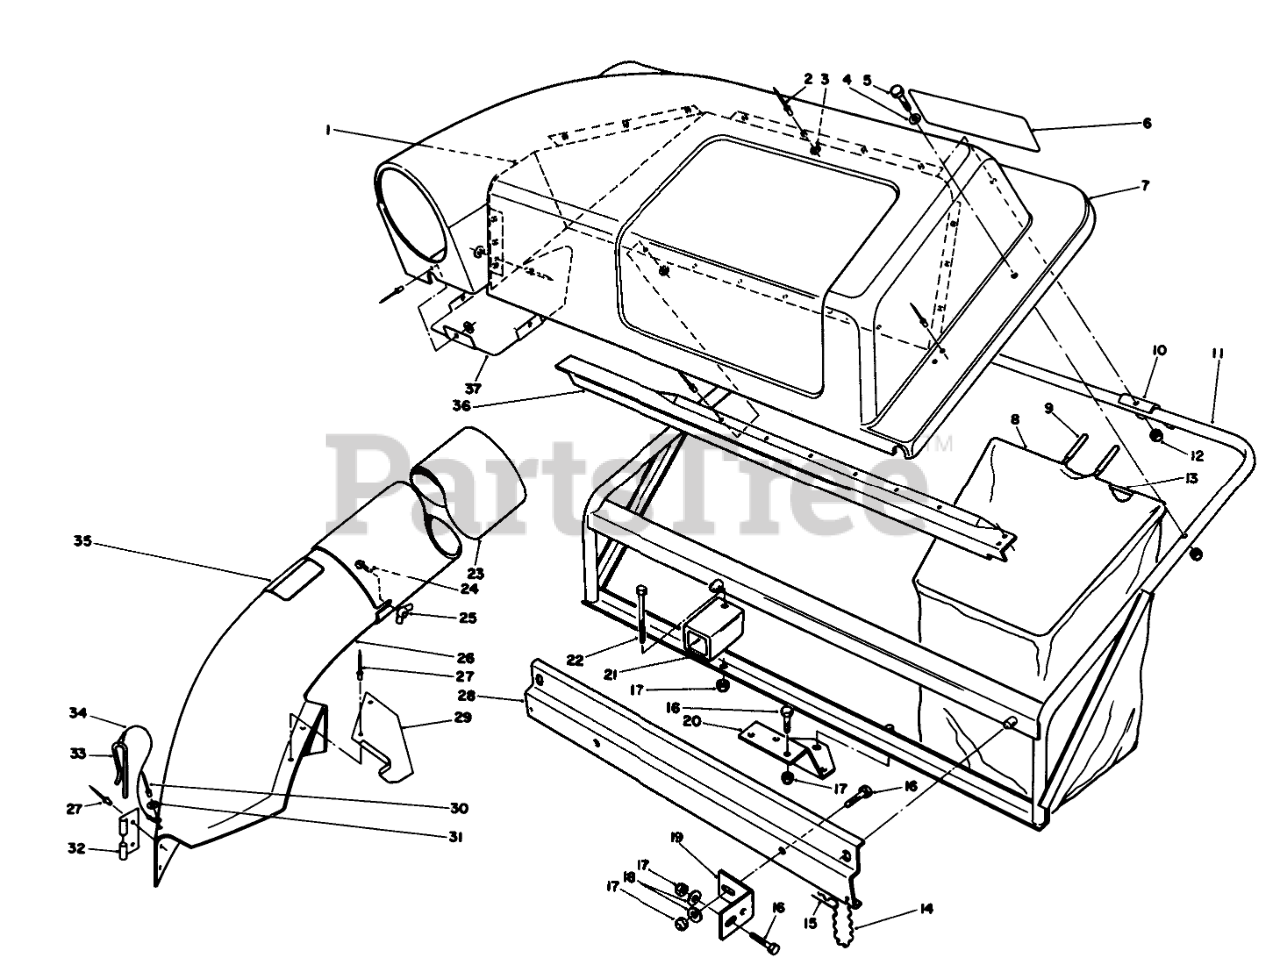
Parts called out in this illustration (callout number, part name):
1	Screen-Cover
2	Rivet-Pop
3	WASHER-FLAT
4	WASHER-PLAIN
5	SCREW-HH
6	TWIN BAGGER DECAL
7	Cover
9	GRIP-HANDLE, BAG
10	BAG FRAME BRKT
11	Frame
12	NUT-LOCK, CAP
13	Frame-Bag
14	Chain
15	PIN-HAIR
16	Screw
17	NUT-LOCK, NI
18	WASHER-PLAIN
19	MTG BRACKET
20	MTG PLATE B
21	FRAME SUPT TUBE B
22	SCREW-HH
23	TUBE(ROUND&LONG)
24	BOLT-CARR
25	NUT-WING SPECL
26	Chute Assembly (Incl. Ref. #27, 29-35)
27	RIVET-BLIND
28	Bracket Frame Support
29	CHUTE SUPT BRKT
30	RIVET-BLIND
31	WASHER-PLAIN
32	BRACKET-MOUNTING, CHUTE
33	PIN-LOCKING, CHUTE
34	LANYARD
35	DECAL-DANGER
36	SCREEN SUPT BRKT B
37	Shield Cover
